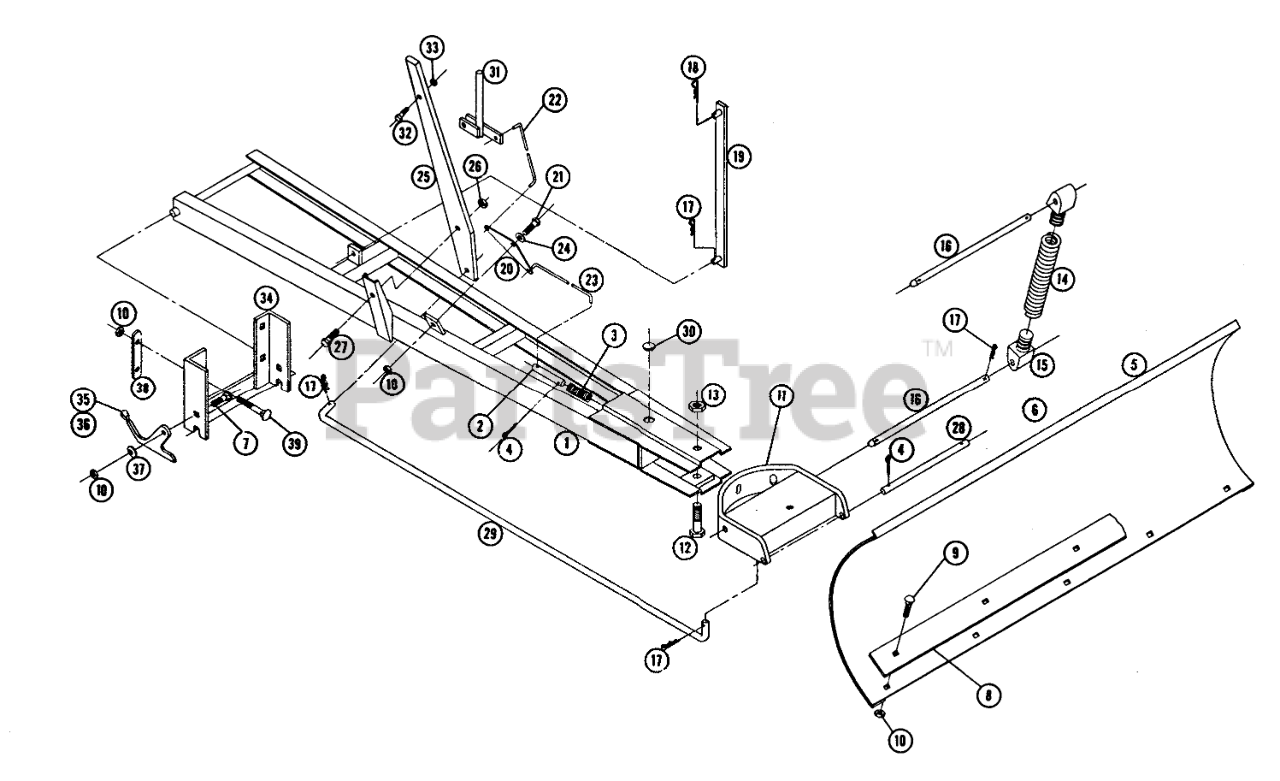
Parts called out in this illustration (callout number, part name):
1	Ass-y-Frame
2	Index Pin
3	SPRING-COMPRESSION
4	Cotter Pin
5	Blade
6	Decal
7	Bolt 3/8-16 x 1
8	Plate
9	Bolt-3/8-16 x 3/4
11	Sector and Channel
12	Bolt-Hex 3/4-16 x 3 3/4
13	Nut-Hex 3/4-16 Elastic Stop
14	Spring
15	Lug
16	ROD-PIVOT, BLADE
17	Hairpin
18	Hair Pin
19	Bar-Lift
20	Index Plate
21	Bolt-Hex 3/8-16 x 1
22	Rod-Upper Index
23	Head-Cylinder
24	Washer
25	Lever
26	Jam Nut
27	Bolt Hex 1/2-13 x 1
28	ROD-LOWER
29	Rod-Blade Control
30	PLUG
31	INDEX LEVER
32	Bolt-Hex 1/4-20 x 1
33	Nut-Nylok
34	Ass-y Bracket-Mtg.
35	Plate-Latching R.H.
36	Plate-Latching L.H.
37	Washer-Spring
38	BRACKET-REAR LINK MOUNTING
39	Bolt-Carriage 3/8-16 x 3 1/4
